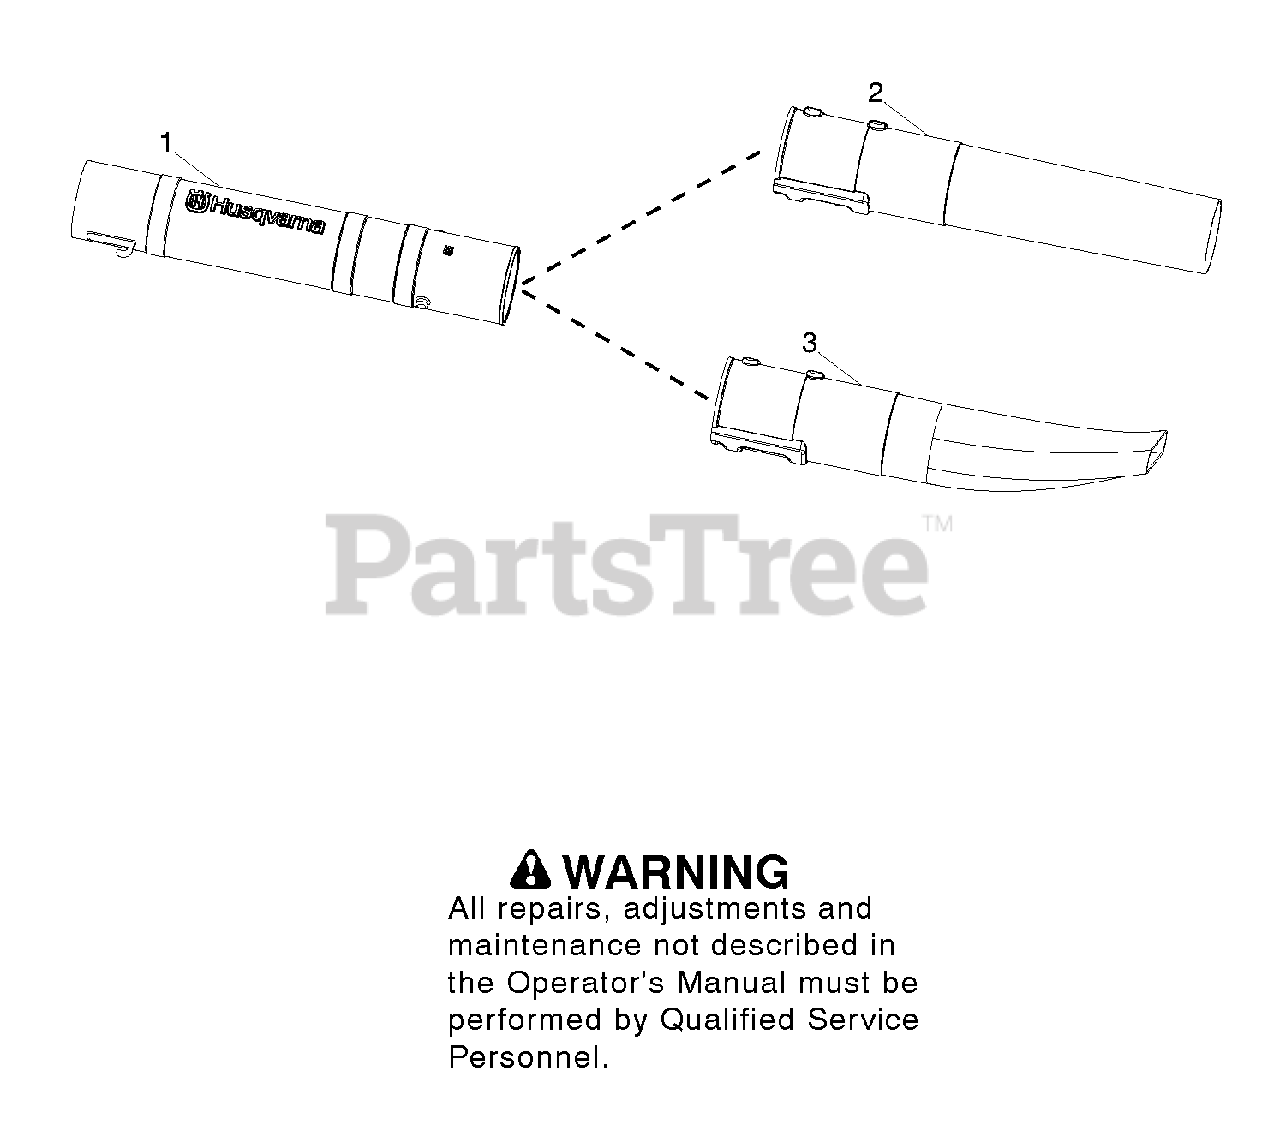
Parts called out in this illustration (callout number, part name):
1	Assy - Tube - Upper Blower w/barrier
2	Tube - Lower Blower
3	Flare - Lower Blower tube
